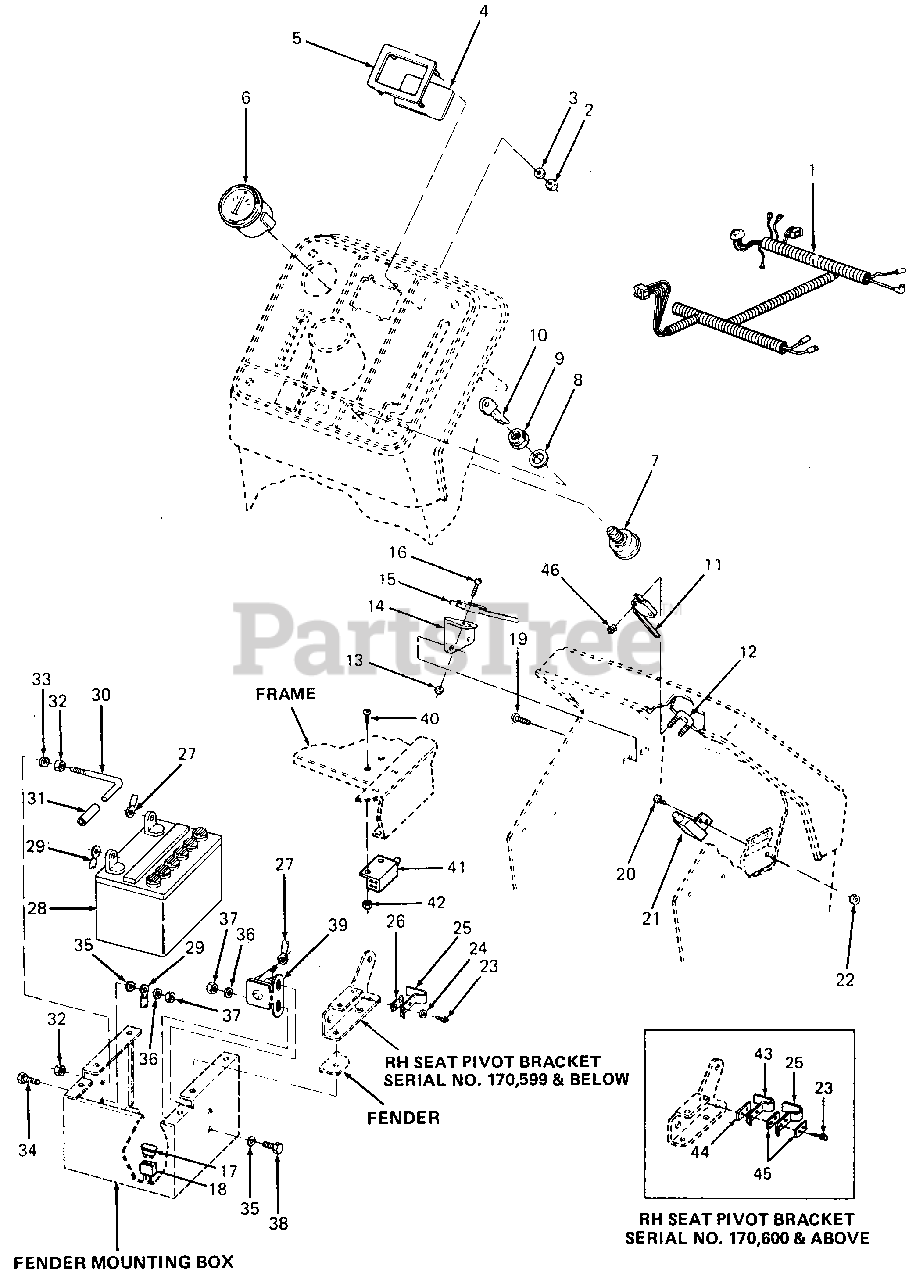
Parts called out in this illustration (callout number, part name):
1	Harness, Wire
2	Nut, Self-Threading
3	Washer, Rubber, .18 X .50 X .06 Thk
4	Label, Indicator
5	Bezel, Light
6	Ammeter
7	Switch, Ignition Key
8	Washer, Flat
9	Nut, Ignition Switch
10	Key, Ignition (Set of 2)
11	Switch, Rev. Micro
12	Screw, Switch
13	Nut, Hex Insert Lock, #4-40
14	Plate, Switch
15	Switch, Micro
16	Screw, Hex Hd Mach, #4-40 X .75 Lg
17	Fuse, Auto Type, 20 Amp
18	Fuse Holder
19	Screw, Hex AB Tapp, 1/4- X .62 Lg
20	Screw, Truss Mach, #10-24 X .50 Lg
21	Switch, Safety
22	Nut, Hex Center Lock, #10-24
23	Screw, Hex Wash Hd AB Tapp, #8 X .50 Lg
24	Washer, Plastic
25	Switch, Spring
26	Plate, Insulator Nut
27	Wire, Positive Battery
28	Battery, 12 Volt
29	Wire, Ground, 11.5 in. Lg
30	Pin, Belt Guard Lock
31	Fuel Line, 2 in. Lg
32	Nut, Hex, 5/16-24 GR5
33	Washer, Lock, 5/16
34	Screw, Hex Cap, 1/4-20 X .62 Lg GR5
35	Washer, Int Ext Lock, 1/4 X 3/4
36	Washer, Flat, .281 X .73 X .063 Thk
37	Nut, Hex Patch Lock, 1/4-20
38	Screw, Hex Cap, 1/4-20 X .50 Lg GR5
39	Solenoid, 12 Volt
40	Screw, #10-24 X .50 Lg
41	Switch, Double Poled Plunger
42	Nut, Hex Center Lock, #10-24
43	Switch, Spring
44	Plate, Insulator Boss
45	Plate, Insulator
46	Nut, Hex Insert Lock, #4-40
